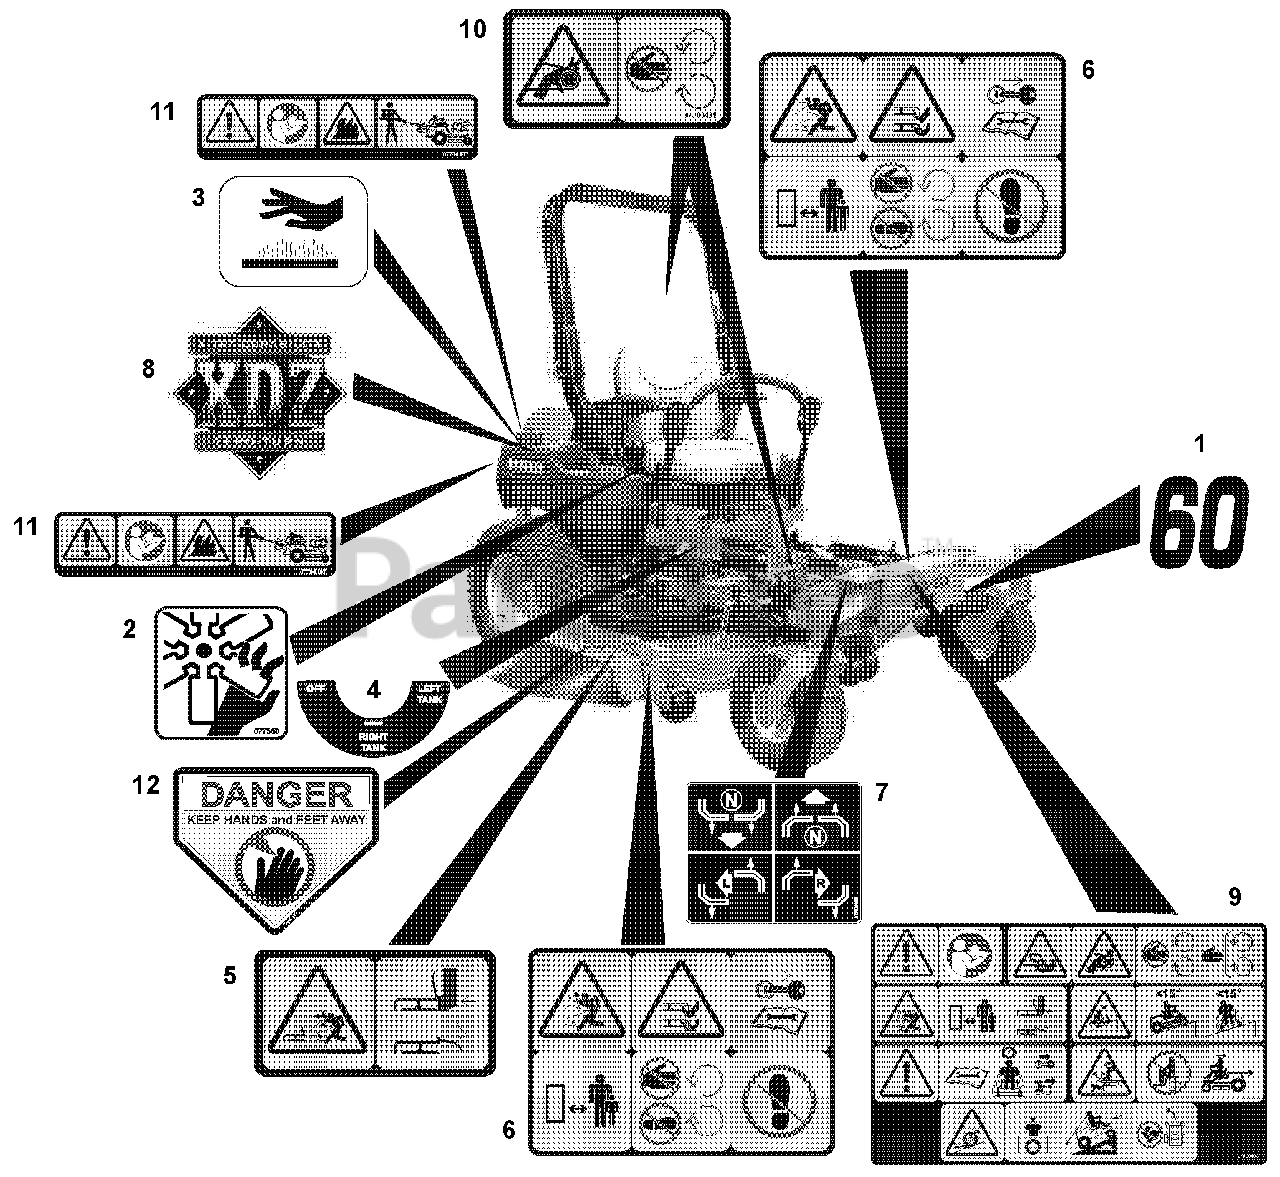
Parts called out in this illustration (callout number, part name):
1	Decal, 60
2	Decal, Danger Fan
3	Decal, Hot Surface
4	Set, Decal Fuel Valve
5	Decal, Safety Deck Guarding
6	Decal, Safety Mower Deck (992217)
7	Decal, Instructional
8	Decal, XDZ
9	Decal, Main Safety Commercial
10	Decal, Safety Guarding
11	Decal, Debris
12	Decal, Danger (992217)
